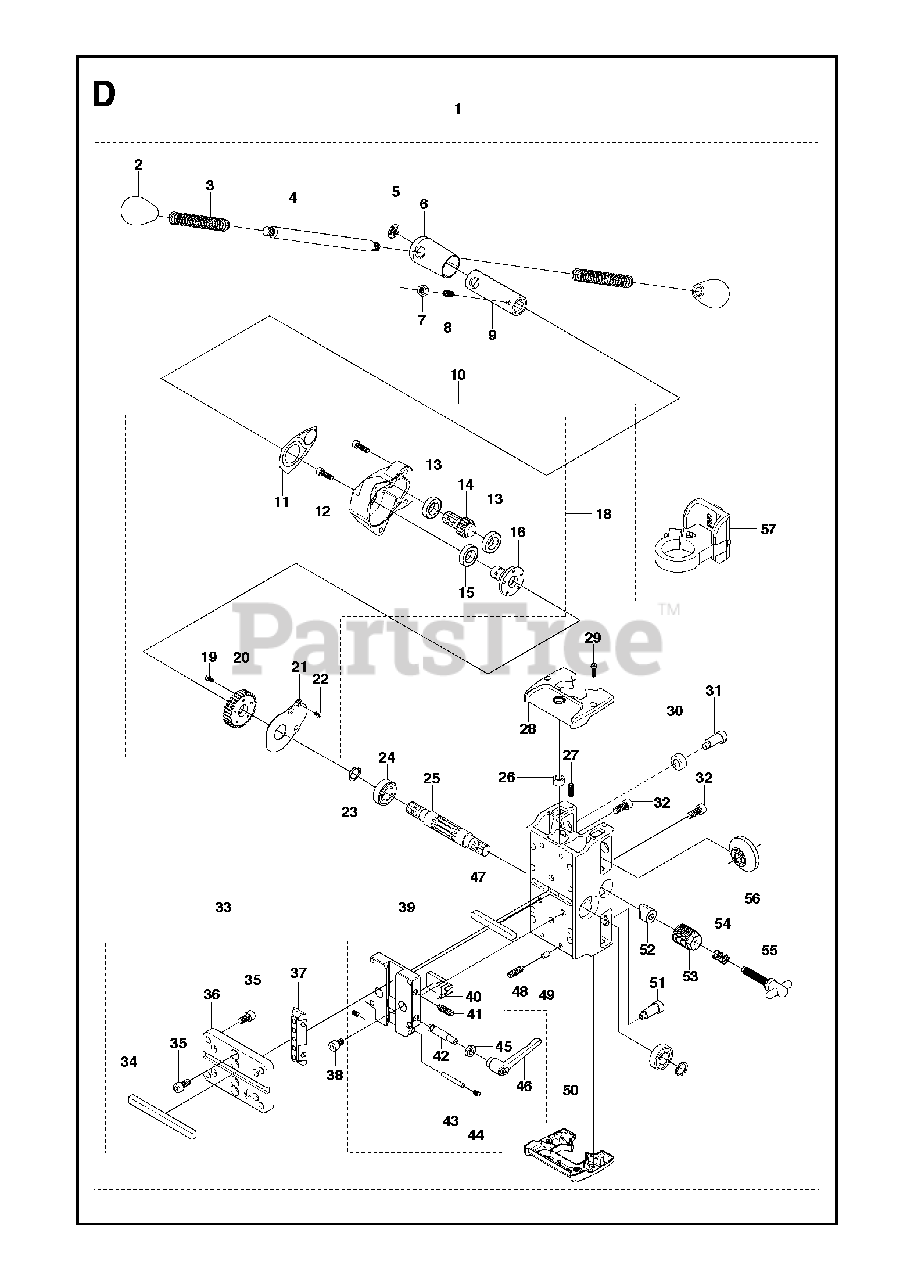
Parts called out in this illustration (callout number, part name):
10	KITNot for Single Speed
12	SCREW IHSCM
18	GEAR WHEEL KITNot for Single Speed
44	SCREW IHSETM
45	HEXAGON THIN NUT
46	INDEXABLE HANDLE, NUT M8
57	ADAPTEROnly for Single Speed
